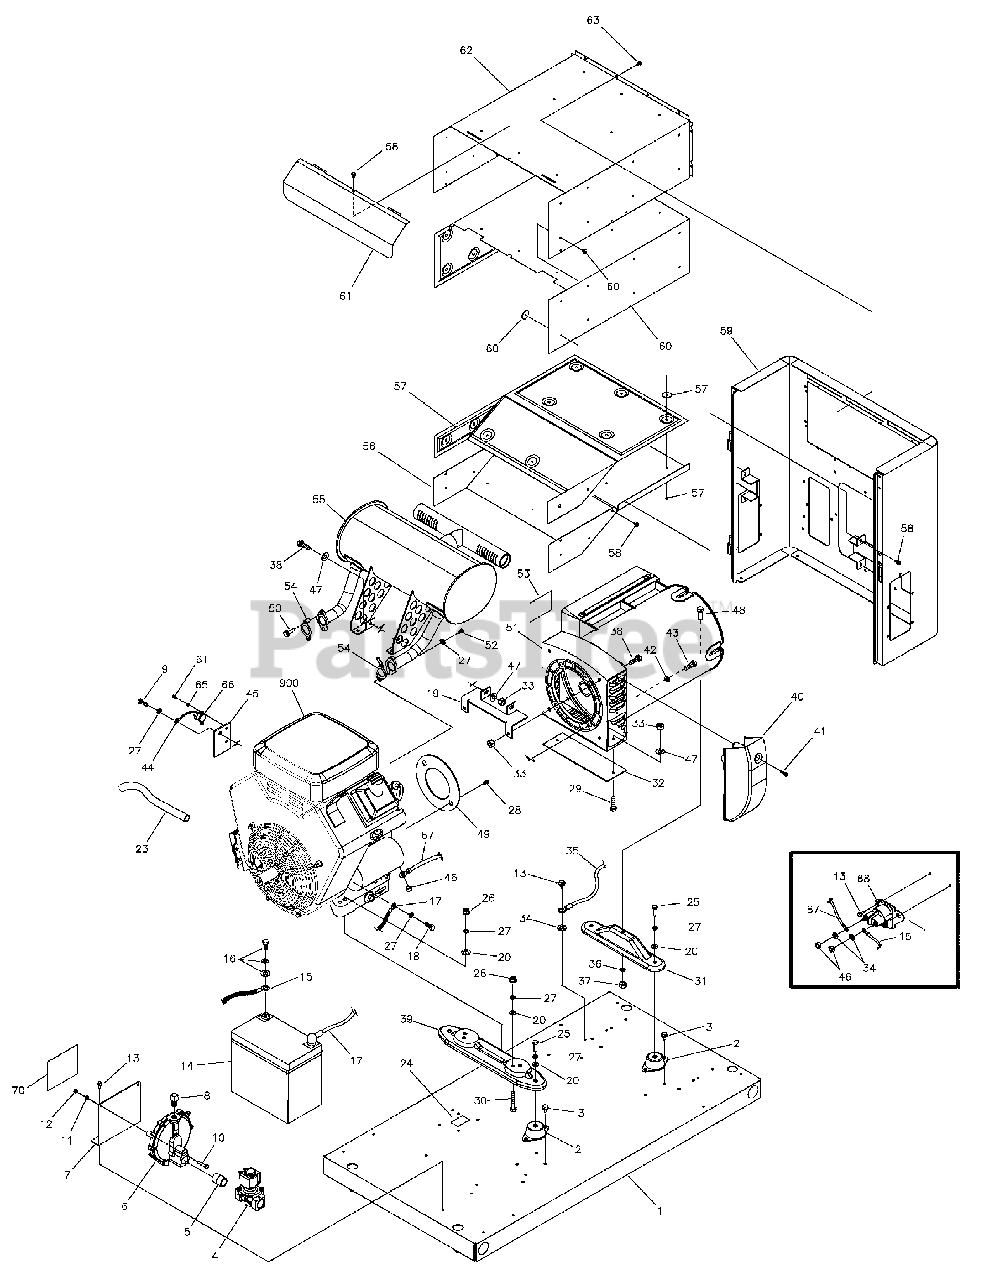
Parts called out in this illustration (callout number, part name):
1	BASE, Mounting
2	MOUNT, Vibration
4	SOLENOID, Gas Fuel
5	FITTING, Coupling
6	REGULATOR, NG/LPG
7	BRACKET, Mounting, Solenoid
8	FITTING, 3/4 Flare to 3/8 NPT
9	* CAPSCREW, Hex Head, M8-1.25 x 12
10	* CAPSCREW, Hex Head, M6-1 x 30
11	* WASHER, Lock, 1/4
12	* NUT, M6-1
13	BOLT
16	KIT, Battery Hardware
18	* CAPSCREW, Hex Head, M8-1.25 x 16
20	* WASHER, Flat, 5/16-M8
23	HOSE, Oil Drain
24	DECAL, Oil Drain
25	* CAPSCREW, Hex Head, 5/16-18 x 1
26	* NUT, 5/16-18
27	* WASHER, Lock, 5/16-M8
28	* CAPSCREW, Hex Head, 5/16-24 x 3/4
29	* CAPSCREW, Hex Head, 1/4-20 x 1
30	* CAPSCREW, Hex Head, 5/16-18 x 1-3/4
31	SUPPORT, Alternator
34	* WASHER, Shakeproof, M6-1/4
36	* WASHER, Lock, M10
37	* NUT, Hex, M10
38	* CAPSCREW, Hex Head, 1/4-20 x 3/4
39	SUPPORT, Alternator
42	* WASHER, Lock, 3/8
43	* CAPSCREW, Hex Head, 3/8-16 x 1-1/4
45	PLATE, Temp Switch
46	* NUT, 1/4-20
47	* WASHER, Flat, M6
48	* CAPSCREW, Hex Head, M10-1-1/2 x 30
50	SCREW
51	ALTERNATOR (see page 6)
53	DECAL, Caution Hot Surface
58	CRIMPTITE, 10-24 x 1/2
59	BULKHEAD, Alternator
61	COLLECTOR, Muffler Box
62	BOX, Muffler Top
63	SCREW, 10-32 x 5/8
64	* SCREW, Phillips Head, 4-40 x 0.19
65	* WASHER, Lock, #4
66	SWITCH, Temp
68	SOLENOID, Starter
70	DECAL, Requirements, Fuel
900	** ENGINE
